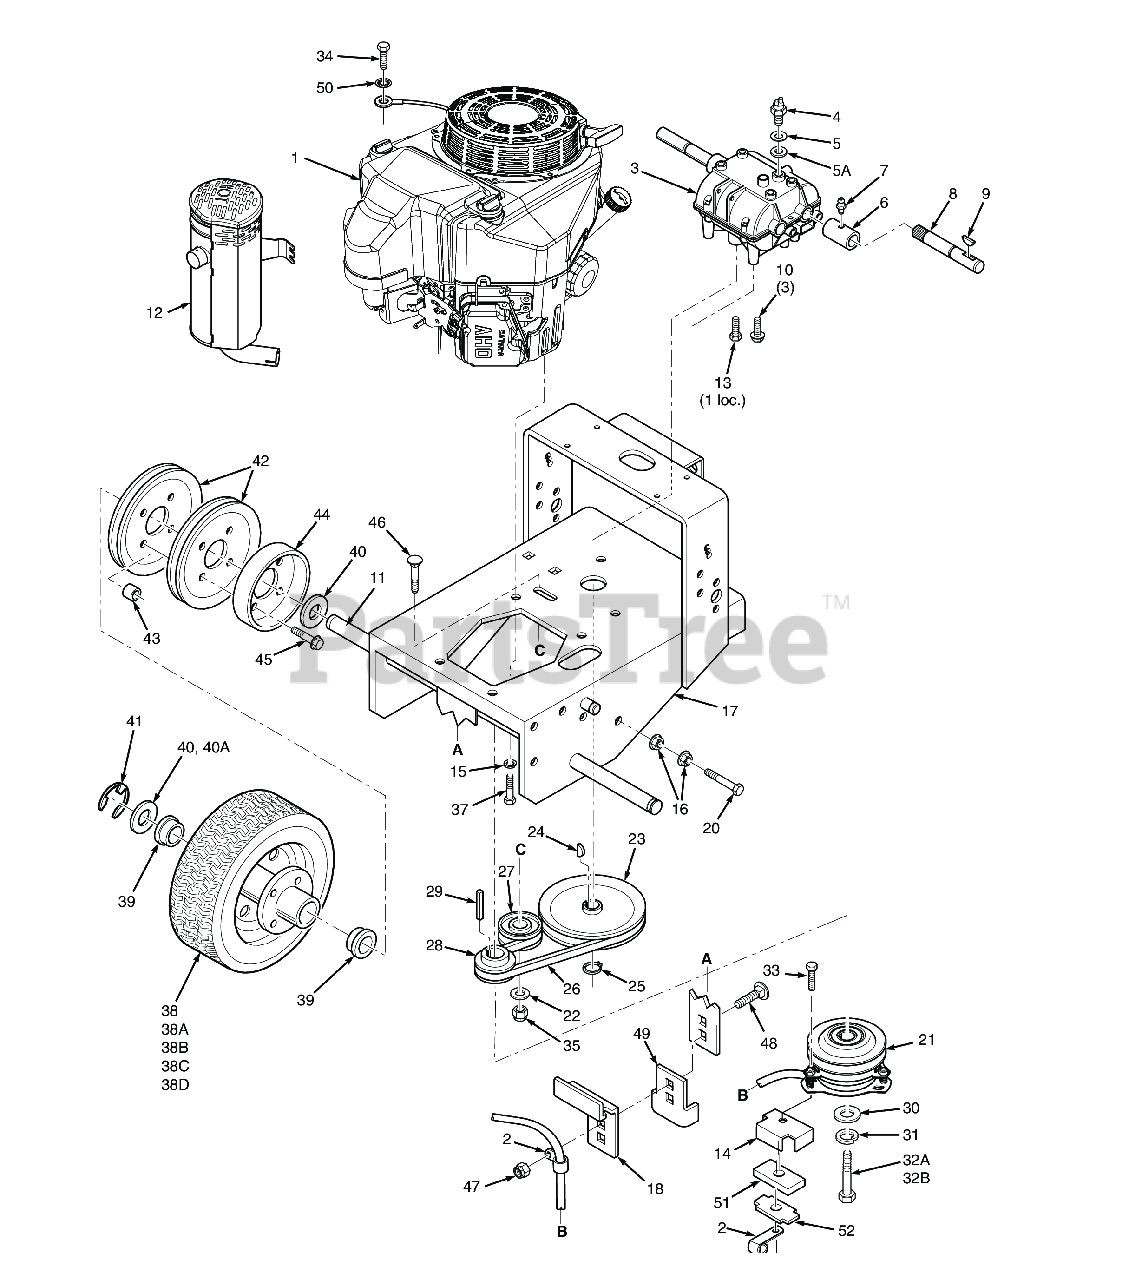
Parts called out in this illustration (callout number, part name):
1	Engine, Kawasaki 14FS (FS481V)
1	Engine, Kawasaki 15FS (FS541V)
2	Clamp, Cable 1/2" I.D.
3	Transmission, 5-speed (Peerless 700-070, 9 tooth spline)
4	SWITCH, TRANSMISSION INTERLOCK N.O.
5	FIBER WASHER - .010
5A	FIBER WASHER - .020
6	Coupler, Jackshaft
7	Greese Fitting, Straight 1/4 - 28
8	Jackshaft (fits SW32,36,48 & 52)
9	KEY, HI PRO #9
10	Capscrew, 5/16-18 x .75 Serrated Flange Hex Head
11	Wheel Axle (SW 32)
12	Muffler, Kawasaki (FS481, FS541, FS600)
13	BOLT, SERRATED FLANGE HEX HEAD 5/16-18 X 3/4"
14	Backing Plate, Clutch Stop
15	Lockwasher, 3/8" Spring, Kawasaki FX / FS
16	NUT, 3/8-16 SERRATED FLANGE HEX HEAD
17	Engine Deck (fits SW32)
18	Plate, Clutch Bracket
19	Nut, Serrated Flange 5/16-18 (Right Front Engine Mounting, Briggs and Kohler Only)
20	Capscrew, Hex Head 3/8-16 x 3-3/4"
21	Clutch, Electric (Ogura)
22	Flatwasher, 3/8" Special (.391 x .938 x .105)
23	PULLEY, TRANSMISSION INPUT
24	KEY, WOODRUFF #9, 3/16 X 3/4"
25	RETAINING RING, 5/8 EXT. - BASIC
26	BELT, TRANSMISSION DRIVE
27	Pulley, Idler 3" Dia. - 52"
28	Pulley, Traction Drive
29	KEY, 1/4 X 1/4 X 3/4"
30	Flatwasher, 7/16-.469 x 1.75 x .25 (48, 52)
31	Lockwasher, 7/16� Spring
32A	Bolt, Hex Head 7/16-20 x 2-1/2" (Kohler)
32B	Cpsrw, M10-1.5 x 55 Metric Hex Hd
33	Bolt, Hex Head 5/16-18 x 1-1/2" - Front
34	Bolt, Hex Head M8 - 1.25 x 16 (48V / 52V)
35	HEX NUT, ELASTIC STOP LOCK, 3/8-16
36	Flatwasher, 5/16-.375 x .875 x .083 (35BV & 37BV-EFI)
37	Bolt, Hex Head 3/8-16 x 1-1/4"
38	WHEEL ASSEMBLY(INCL. 38C-38D)(FITS SW32)
38A	Tire, 13 x 6.50-6, 2-ply (fits SW36, 48, 52)
38B	Rim & Bearing Assembly (fits SW36, 48, 52)
38C	Tire, 13 x 5.00-6 2-ply (SW32 only)
38D	Rim Assembly (incl. 39) (SW32 only)
39	Wheel Brng. NWC (OD 1.984 - 1.980)
40	Flatwasher, 1" (1.062 x 1.75 x .10)
40A	Flatwasher, 1" (1.062 x 1.50 x .048")
41	Ring, Retaining 1" External "E"
42	PULLEY, WHEEL DRIVE
43	SPACER, WHEEL PULLEY
44	BRAKE DRUM
45	Bolt, Serrated Flange Hex Head 5/16-18 x 1.50"
46	SHORT SQUARE NECK CARRIAGE BOLT, 3/8-16 X 2"
47	HEX NUT, ELASTIC STOP LOCK, 5/16-18
48	Bolt, Carriage 5/16-18x1" (large frame units only)
49	Plate, Clutch Anti-Rotation
50	Lockwasher, 5/16" Ext. Tooth (Kohler x1)
51	Rubber Pad, Clutch Stop
52	Plate, backing Clutch Pad
